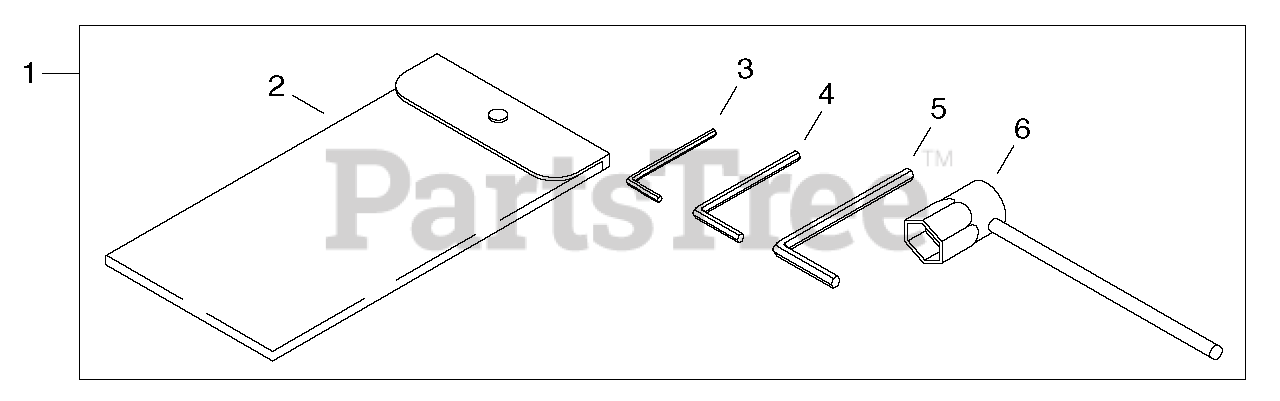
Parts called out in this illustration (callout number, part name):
1	TOOL KIT, SERVICE
2	BAG, TOOL
3	WRENCH, ALLEN 3 MM
4	WRENCH, ALLEN 4 MM
5	WRENCH, ALLEN 5 MM
6	T-WRENCH 19 MM
